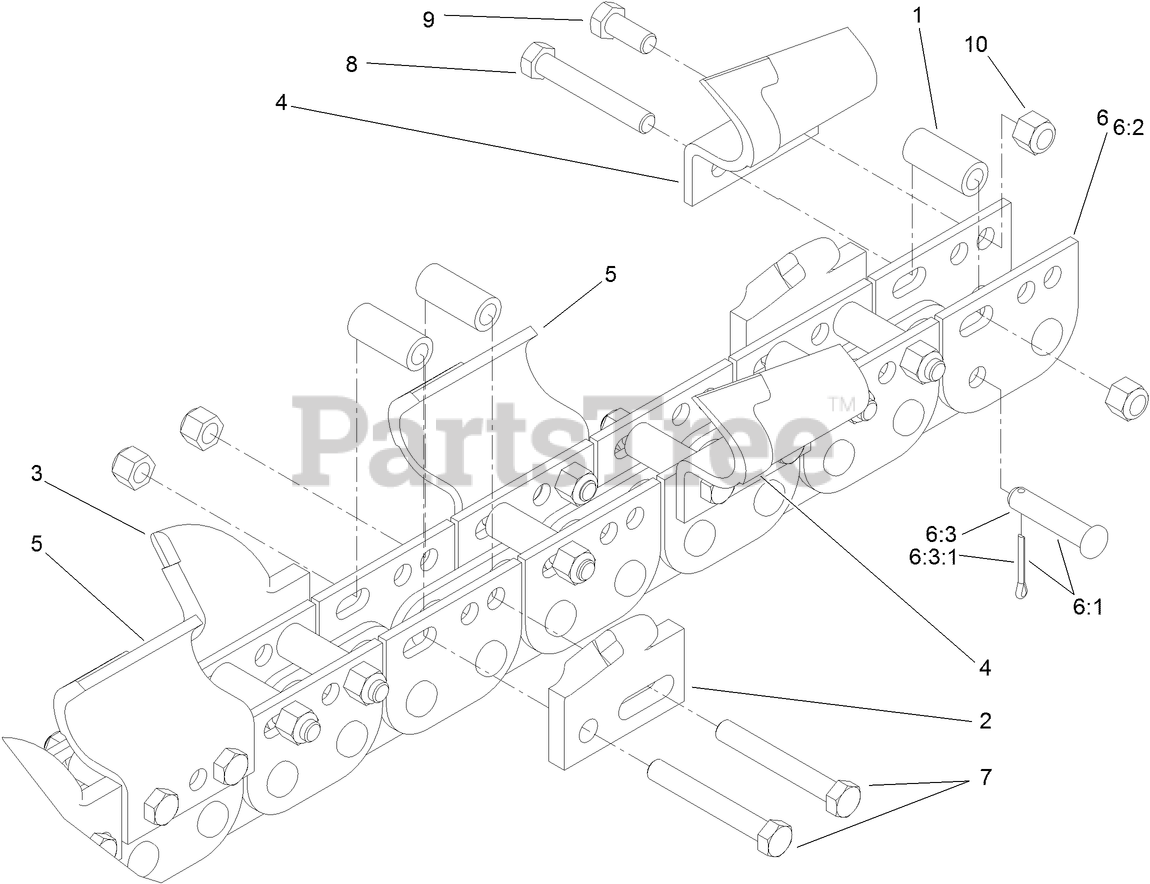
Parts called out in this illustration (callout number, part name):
1	SPACER-TUBE
2	TOOTH- ROCK, LH
3	TOOTH-ROCK, RH
4	TOOTH-SOIL, LH
5	TOOTH-SOIL, RH
6	CHAIN-BARE, 32 STATION
6:1	PIN-CONNECTING
6:2	LINK REPAIR KIT
6:3	PIN-CONNECTING (61MM)
6:3:1	PIN-COTTER
7	SCREW-HH
8	SCREW-HH
10	NUT-HEX
